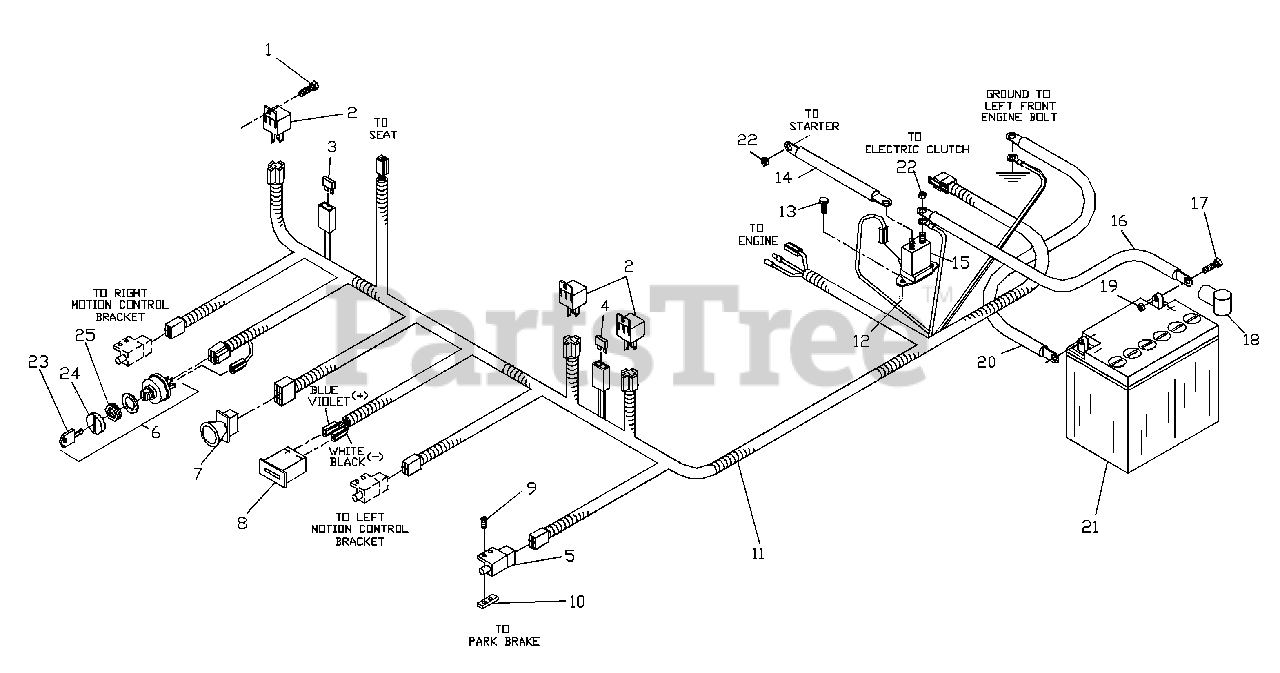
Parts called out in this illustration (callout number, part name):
1	#10 X 1/2 SELF TAPPING
3	7.5 AMP 32 VOLT ATO FUSE
4	20 AMP 32 VOLT ATO FUSE
5	INTERLOCK SWITCH
6	IGNITION SWITCH
7	BLADE SWITCH
8	HOUR METER
9	#10-24 X 5/8
10	TAPPED PLATE
11	WIRING HARNESS
12	NUT 1/4C CENTERLOCK
13	HCS 1/4C X 5/8
14	CABLE POSITIVE
16	CABLE POSITIVE, LONG
17	HCS 5/16C X 3/4
19	NUT 5/16C CENTERLOCK
20	CABLE NEG.
21	BATTERY
22	NUT 1/4C NYLOC
23	KEY, PADDED
